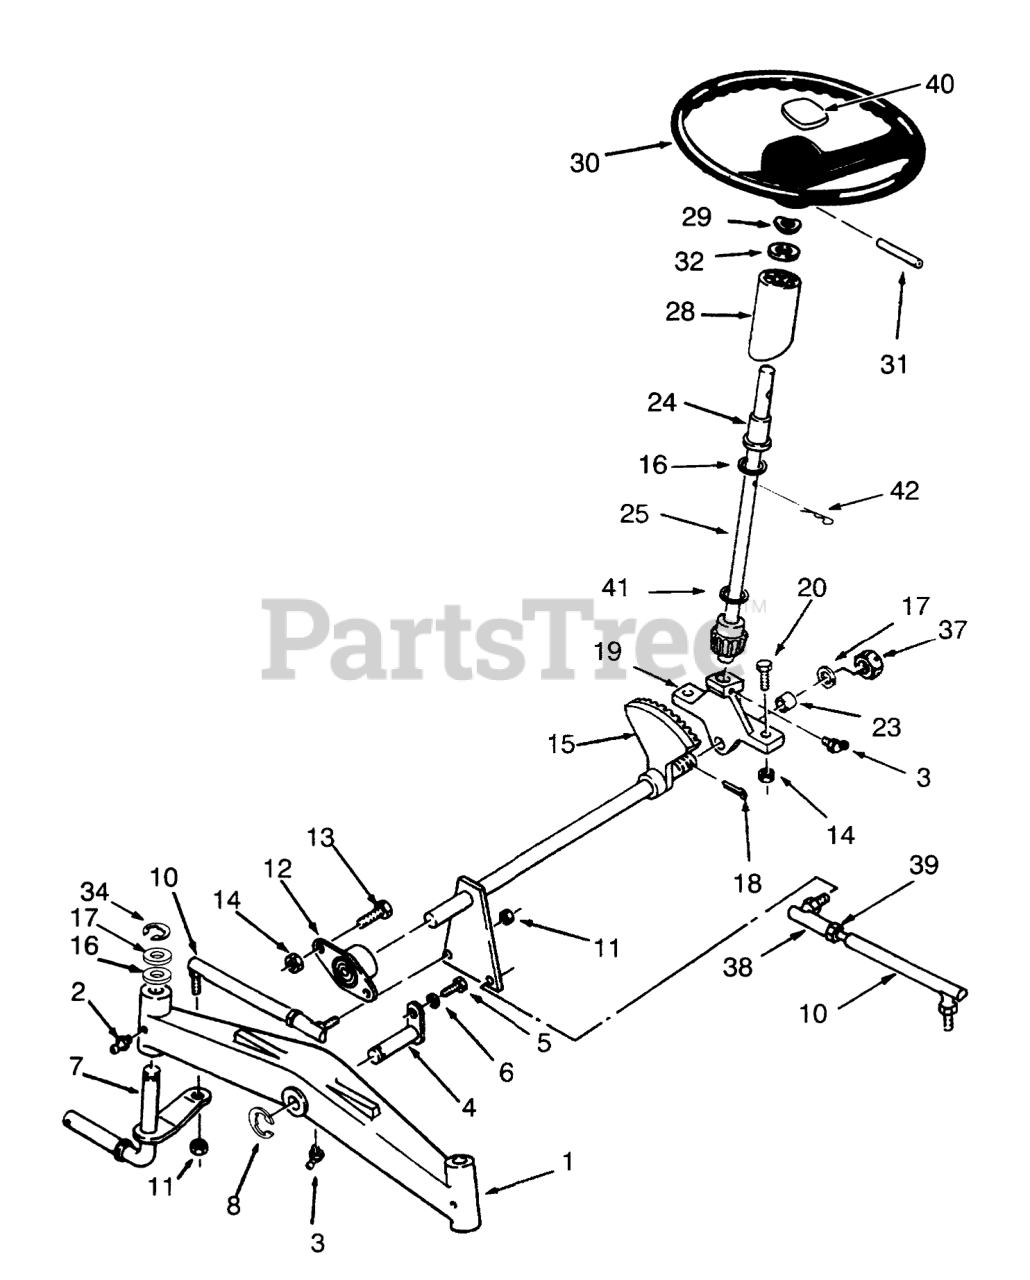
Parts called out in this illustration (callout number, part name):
1	AXLE-FRONT
2	FITTING-GREASE
3	FITTING-GREASE
4	PIN AND PLATE ASM
5	SCREW-HH
6	WASHER-LOCK
7	LH SPINDLE ASM
8	E-RING
10	Tie Rod Assembly (Incl. Ref. # 38 & 39)
11	NUT HEX 3/8-24 E.S.
12	BEARING-FLANGED
13	SCREW-HH
14	NUT-LOCK, NI
15	Shaft
16	WASHER-SHIM
17	WASHER
18	PIN-COTTER
19	Support-Steering
20	SCREW-HH
23	BEARING-BRONZE
24	BEARING-FLANGED
25	STEERING SHAFT ASM
28	TUBE-STEERING
29	WASHER-BOWED
30	Steering Wheel (Incl. Ref. #40)
31	PIN-ROLL
32	WASHER-FLAT
34	RING-RETAINING
37	NUT-HEX, SLOTTED
38	BALL-JOINT
39	NUT-6
40	STRG-WHL INSERT TORO
41	O-RING
42	PIN-COTTER
